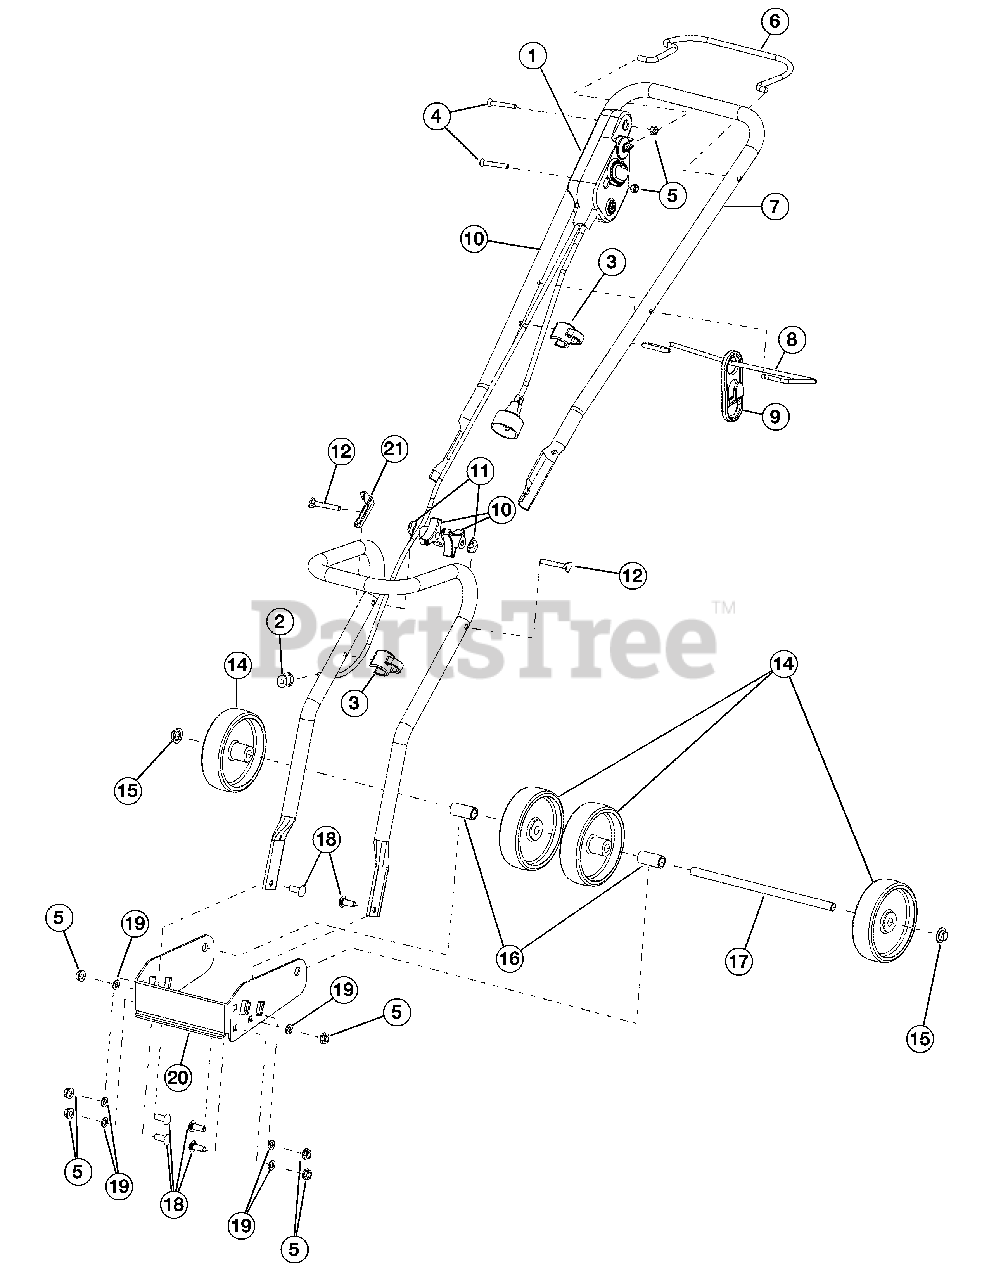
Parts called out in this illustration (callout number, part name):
1	Switch Asm
2	Bushing
3	Cable guide
5	Nut
7	Upper Handle
8	Guide Bar
9	Cord Restraint
11	Washer
13	Lower Handle
15	Push Cap
16	Spacer
18	Bolt
19	Washer
20	Wheel Bracket
21	Control Rod Bracket
